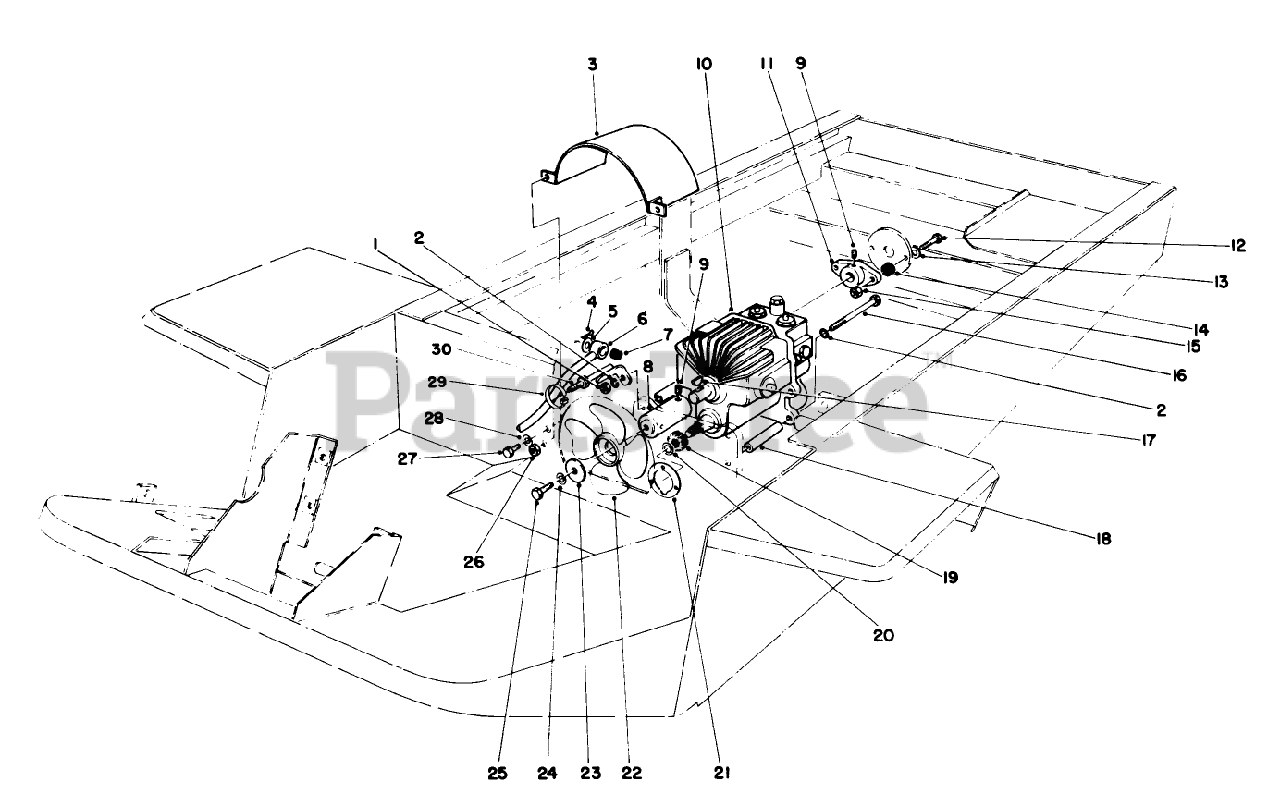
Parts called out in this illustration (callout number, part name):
1	NUT-HEX
2	WASHER-LOCK
3	Fan Shroud
4	PIN-COTTER
5	WASHER-FLAT
6	PUMP CONTROL TUBE WA
7	BUSHING-RUBBER
8	Hub & Plug
9	SCREW-SET, HSH
10	Transmission
11	HUB-PUMP
12	SCREW-HH
13	WASHER-FLAT
14	SPACER-RUBBER COUPLNG
15	NUT-HEX
16	SCREW-HH
17	KEY-WOODRUFF
18	SPACER-MOUNTING
19	Gear
20	Ring-Snap
21	GASKET-TRANSMISSION
23	WASHER
24	WASHER-LOCK
25	SCREW-HH
26	NUT-JAM
27	SCREW-HH
28	WASHER-LOCK
29	TIE-CABLE
30	Axle Support
